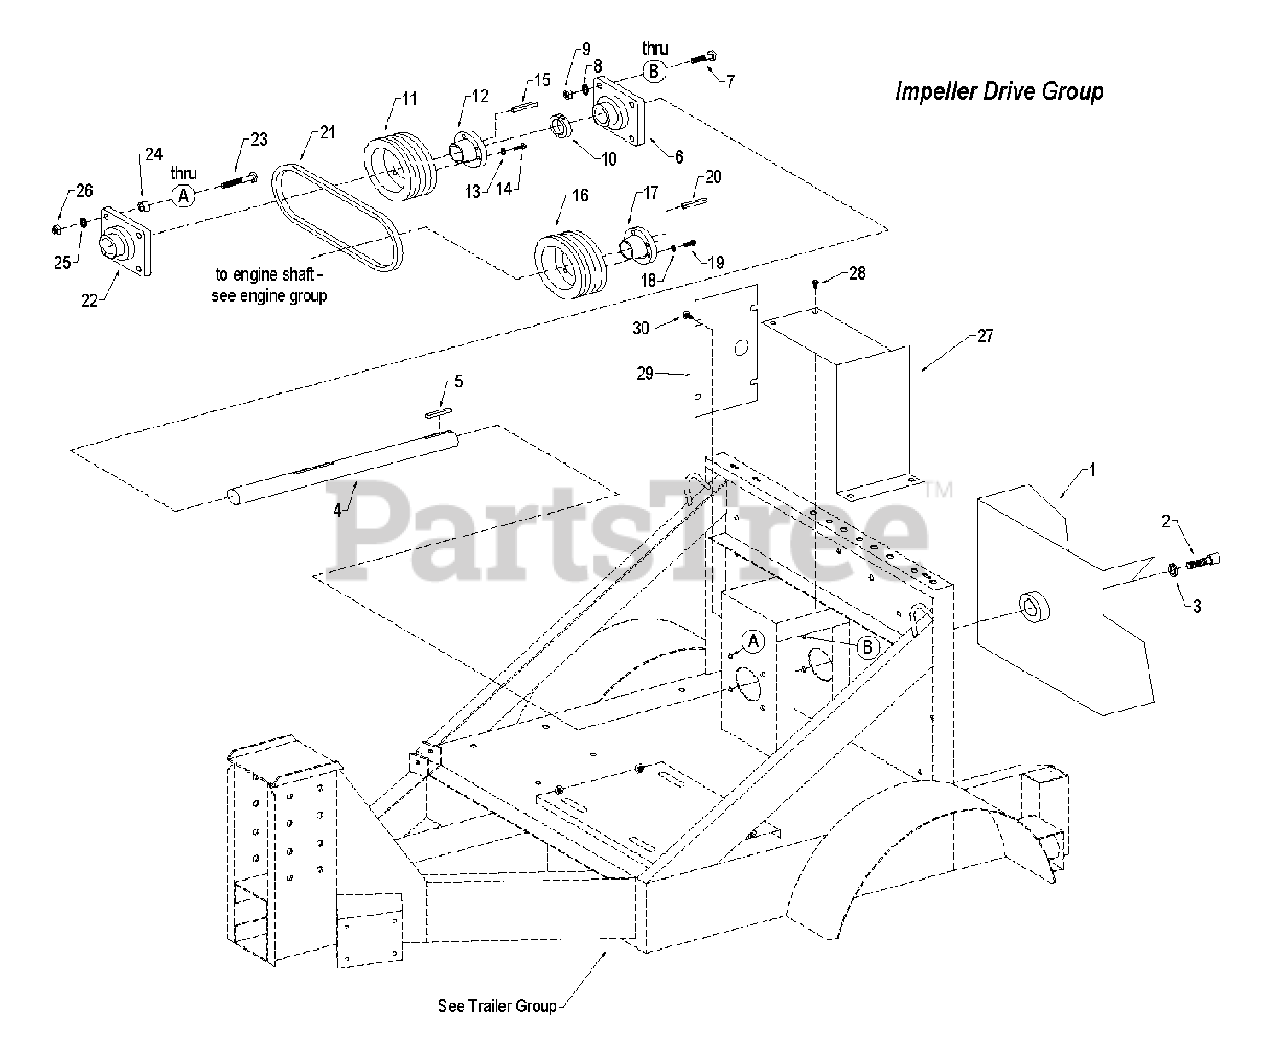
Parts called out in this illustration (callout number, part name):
2	Bolt, impeller – 5/8-11 x 2
3	Washer, lock - 5/8"
4	Shaft, impeller
5	Key, impeller
6	Bearing unit - 1-7/16
7	Bolt, hex - 1/2-13 x 1-1/2"
8	Washer, lock - 1/2"
9	Nut, hex - 1/2-13
10	Collar, split, 2 pc - 1-7/16
11	Pulley, impeller drive
12	Bushing, pulley - SKX1-7/16
13	Washer, lock – 5/16 – supplied with bushing #12
15	Key, shaft
16	Pulley, impeller drive
17	Bushing, pulley - SKX1-1/2
18	Washer, lock – 5/16 – supplied with bushing #12
20	Key, shaft
21	Belt, impeller drive - 3VX450
22	Bearing unit - 1-7/16
23	Bolt, hex - 1/2-13 x 2"
24	Spacer - 1/2 id x 5/8
25	Washer, lock - 1/2"
26	Nut, hex - 1/2-13
27	Cover, Drive belt top
28	Bolt, 'F' thread - 5/16 x 3/4
29	Cover, Drive belt side
30	Bolt, 'F' thread - 5/16 x 3/4
